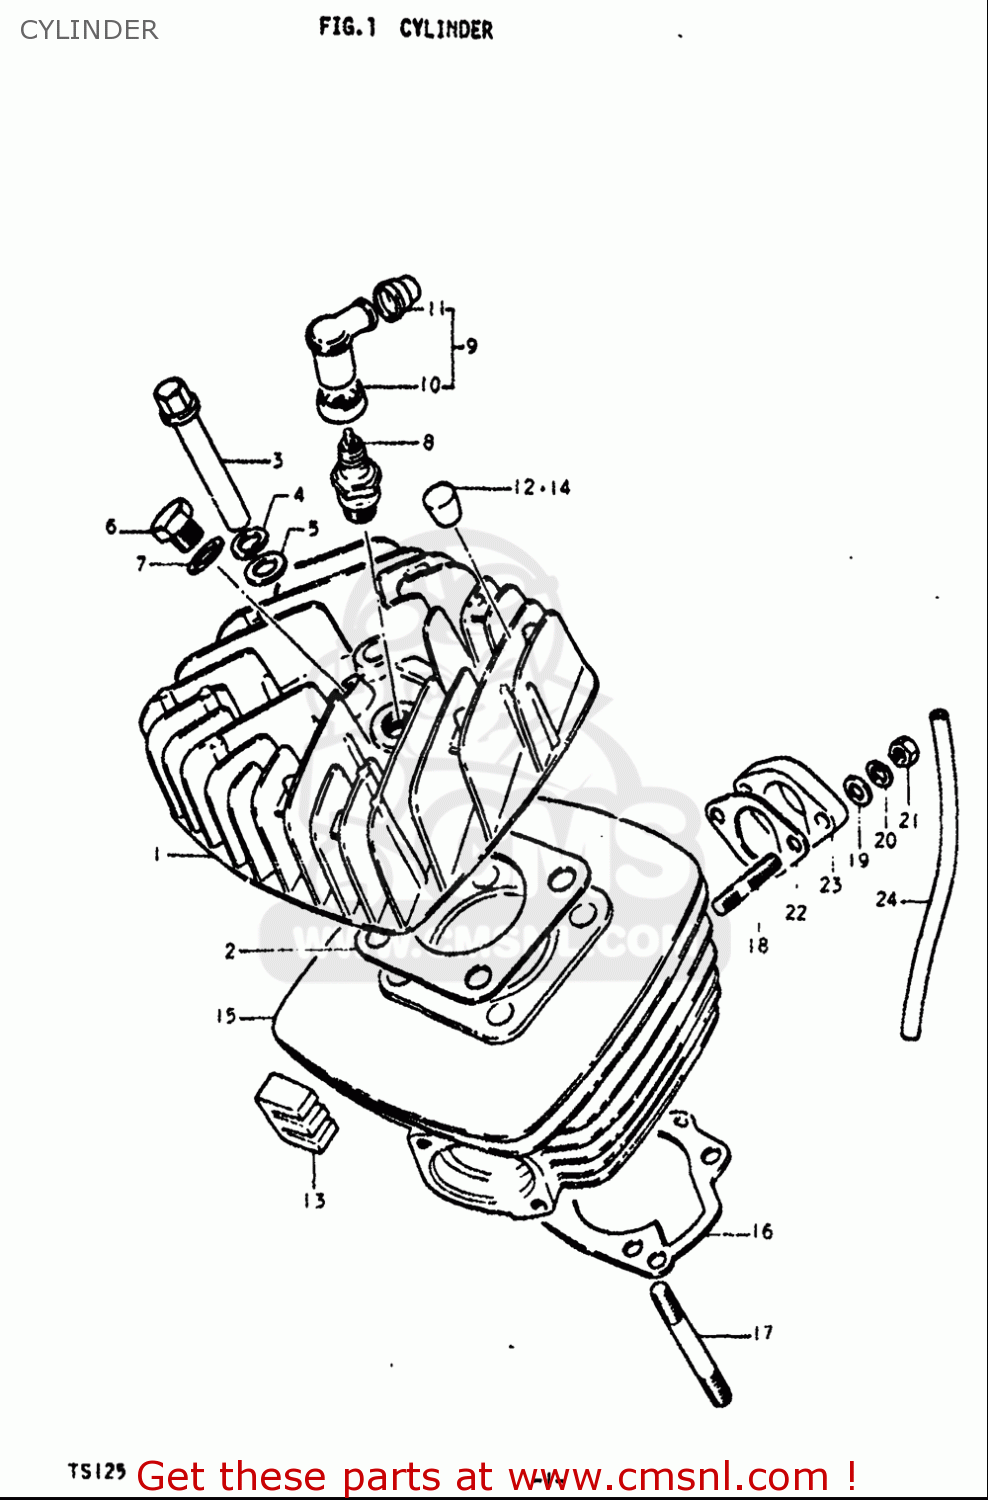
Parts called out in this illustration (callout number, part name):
2	GASKET,CYLINDER HEAD (NAS)
3	NUT
4	WASHER,LOCK
5	WASHER
6	PLUG
7	GASKET(14X19.2X2) (NAS)
8	PLUG,SPARK(B7HS)
9	CAP,SPARK PLUG
10	SEAL,SPARK PLUG
11	SEAL,HIGH TENSION CORD
12	PAD,CYLINDER
13	PAD,CYLINDER
16	GASKET,CYLINDER (NAS)
17	BOLT,STUD
18	BOLT,STUD
19	WASHER
20	WASHER,LOCK
21	NUT
24	HOSE(3X5X600)
